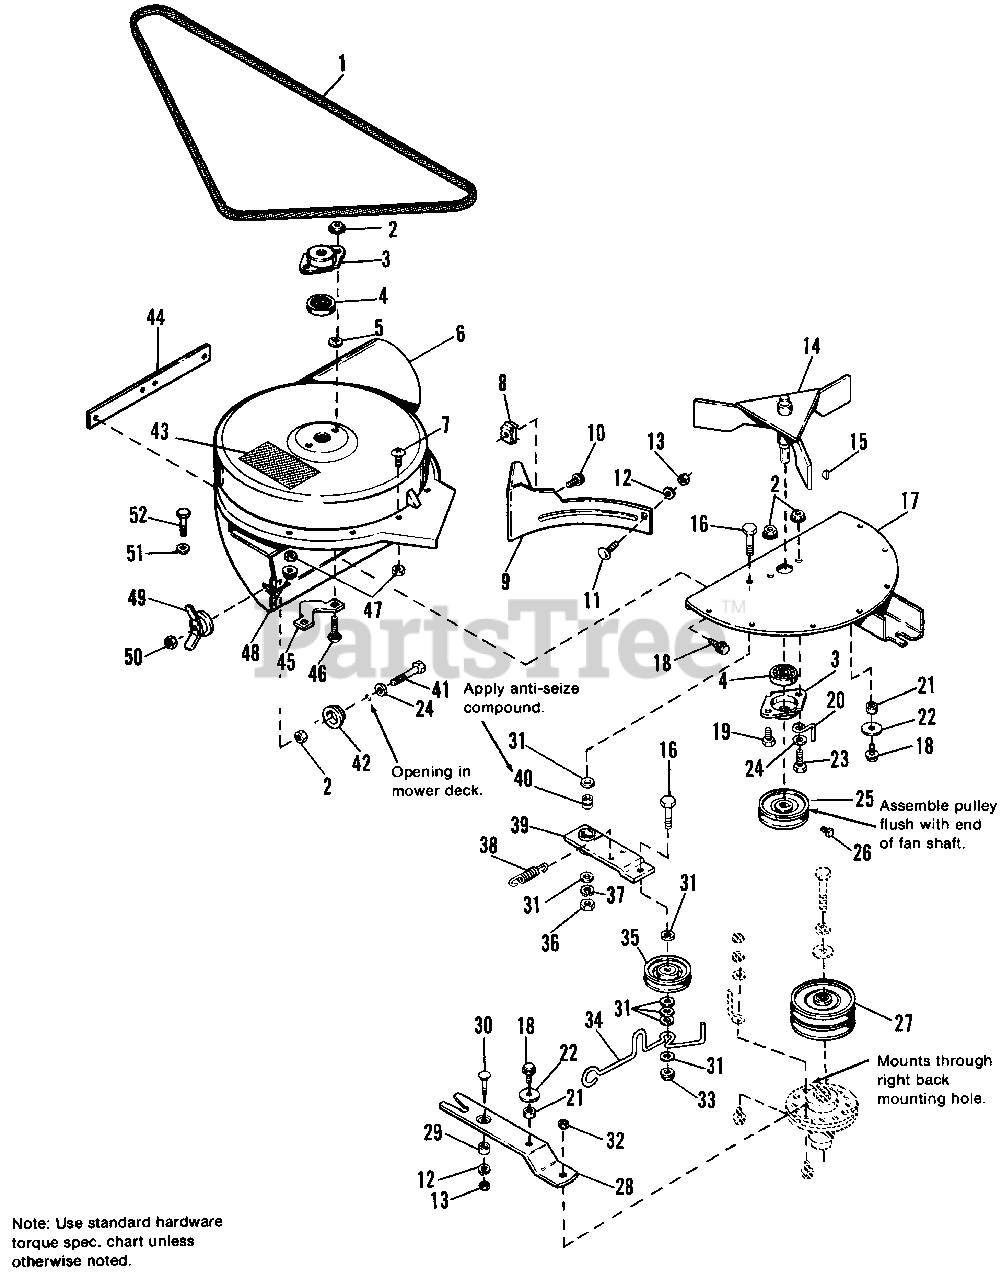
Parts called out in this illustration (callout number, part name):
1	BELT
2	NUT, Flange Lock, 5/16-18
3	BEARING, Retainer
5	PUSHNUT, 5/16
6	HOUSING ASSY., (Indl. Ref. No. 53)
7	SCREW, Truss Hd., 1/4-20 x 5/8
8	NUT, Retainer, 1/4-20
10	SCREW, Whizlock 1/4-20 x 1/2
11	CARRIAGE BOLT, 1/4-20 x 5/8
12	LOCKWASHER, 1/4
13	NUT, Hex Full, 1/4-20
14	FAN ASSY.
15	KEY, Woodruff
16	CAPSCREW, 3/8-16 x 1-3/4
17	PLATE ASSY.
18	SCREW, Taptite, 1/4-20 x 5/8
19	CAPSCREW, Hex Hd., 5/16-18 x 1/2
20	STOP, Belt
22	WASHER, Special
23	CAPSCREW, Hex Thin Hd., 5/16-18 x 3/4
24	WASHER, Plaing, 11/32
25	PULLEY, Driven
26	SETSCREW, 5/16-18 x 1/2
27	PULLEY ASSY.
30	CARRIAGE BOLT, 1/4-20 x 1-1/4
31	WASHER, Plain 13/32
32	NUT, Hex Jam Lock, 5/16-18
33	NUT, Hex Flange Lock, 3/8
34	LEVER, Belt, Retainer
35	PULLEY, Idler
36	NUT, Hex Full, 3/8-16
37	LOCKWASHER, 3/8
38	SPRING, Tension
39	IDLER ARM ASSY.
40	SPACER
41	CAPSCREW, Hex, 5/16-18 x 2-1/2
43	DECAL, Danger
44	STRIP, Reinforcement
45	PLATE, Flange
46	CARRIAGE BOLT, 5/16-18 x 3/4
47	NUT, Hex, Lock, Nylon, 1/4-20
48	NUT, Hex, Flange Lock, 1/4-20
50	NUT, Hex, Full, Lock, 5/16-18
51	WASHER, Plain, 1/4
52	CAPSCREW, Hex, 1/4-20 x 1
